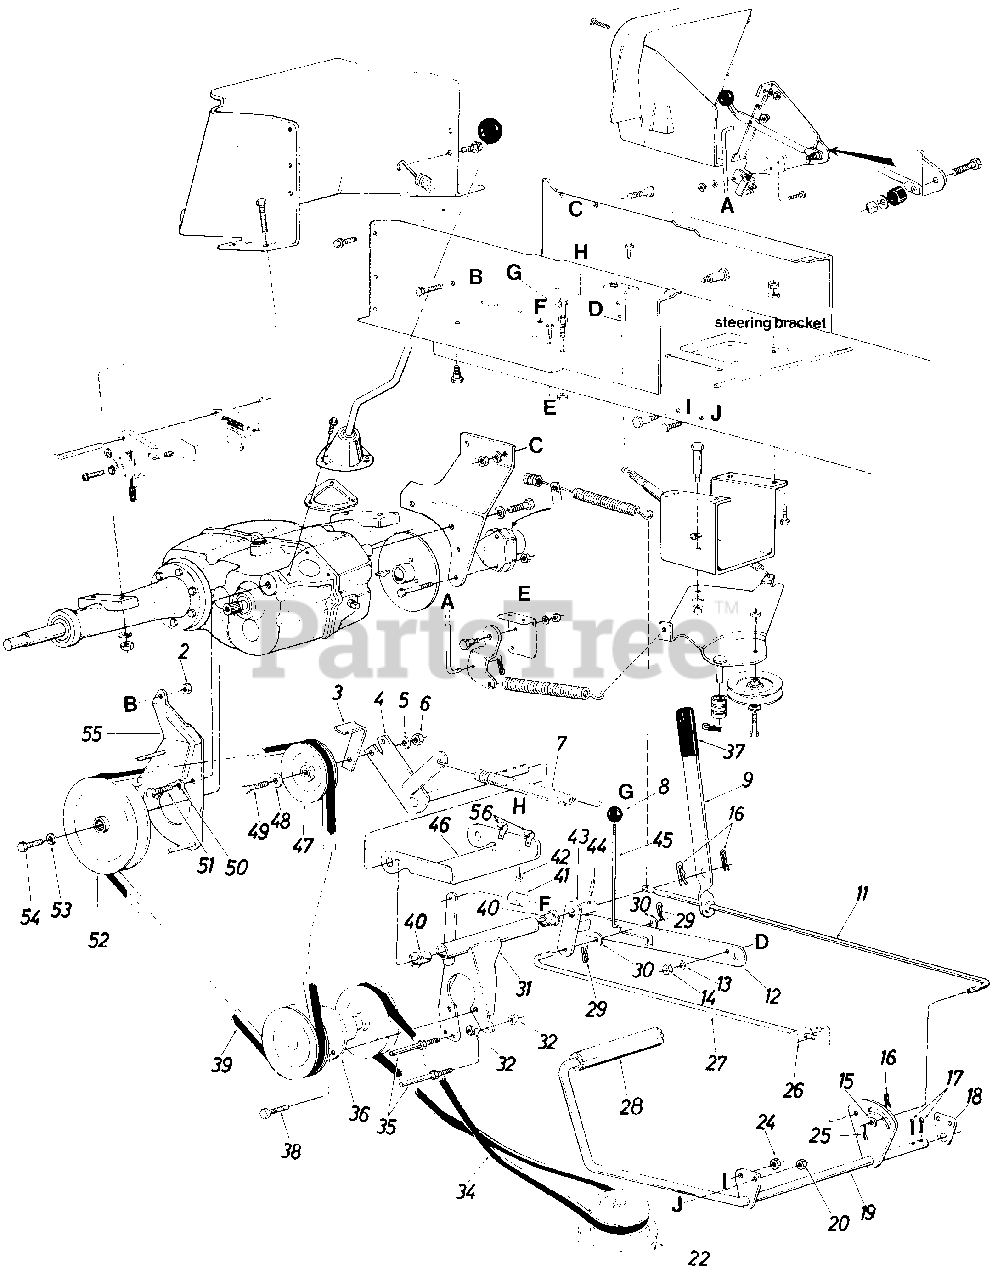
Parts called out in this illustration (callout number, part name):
2	Hex L-Nut 3/8-16 Thd.
5	L-Wash. 318" I.D.
6	Hex Nut 3/8-16 Thd.
7	Ext. Spring (Drive Idler)
8	Knob (Parking Brake)
9	Hand Brake Lever
9	Hairpin Cotter 3/8" Rod
11	Brake Rod
12	Parking Brake Cam
13	L-Wash. 5/16" I.D.t
14	Hex Nut 5/16-18 Thd.
15	Fl-Wash. 5/16" I.D.
16	Hairpin Cotter 3/8" Rod
17	Cotter Pin 1/8" Dia. x 1.00" Lg.
18	Clutch Rod Brg. Brkt.
19	Clutch Brake Pedal Ass'y.
20	Hex Cent. L-Nut 3/8-16 Thd.
22	Engine Pulley 4.75 & 5.56
24	Hex Cent. L-Nut 3/8-16 Thd.*
25	Cotter Pin 3/32" Dia. x .75" Lg.
26	Pivot Bushing
27	Brake Cam Rod
28	Foot Pad
29	Hairpin Cotter 3/8" Rod
30	Fl-Wash. 3/8n l.D. x 1.00" O.D. x .030
31	Jack Shaft Mtg. Brkt. Ass'y.
32	Hex Top L-Nut 3/8-16 Thd.
34	V-Belt
35	Stud 3/8-16 x 3.62" Lg. Special
36	Jack Shaft Ass'y.
37	Flat Grip
38	Hex Sem Scr. 5/16-18 x .75" Lg.
39	V-Belt
40	Nyliner 518" I.D. x .88" Lg.
41	Ext. Spring (Jack Shaft)
42	Hex Thd. Rolling Scr. 1/4-20 x .50" Lg.
43	Clutch-ldler Horn Ass'y.
44	Spring Pin Spiral 1/4" Dia. x 1.00" Lg.
45	Parking Brake Link
46	Idler Mtg. Brkt. Drive
47	4" "V"-ldler Pulley
48	Fl-Wash. 318" I.D.
49	Hex Bolt 3/8-16 x 1.75" Lg.*
50	L-Wash. 318" I.D.
51	Hex Bolt 3/8-16 x .75" Lg.
52	V-Pulley 7.0" O.D. (Transaxle)
53	L-Wash. 318" I.D.
54	Hex Scr. 3/8-24 x .75" Lg.
55	Belt Guard Ass'y.
56	Plastic Hose Clamp
